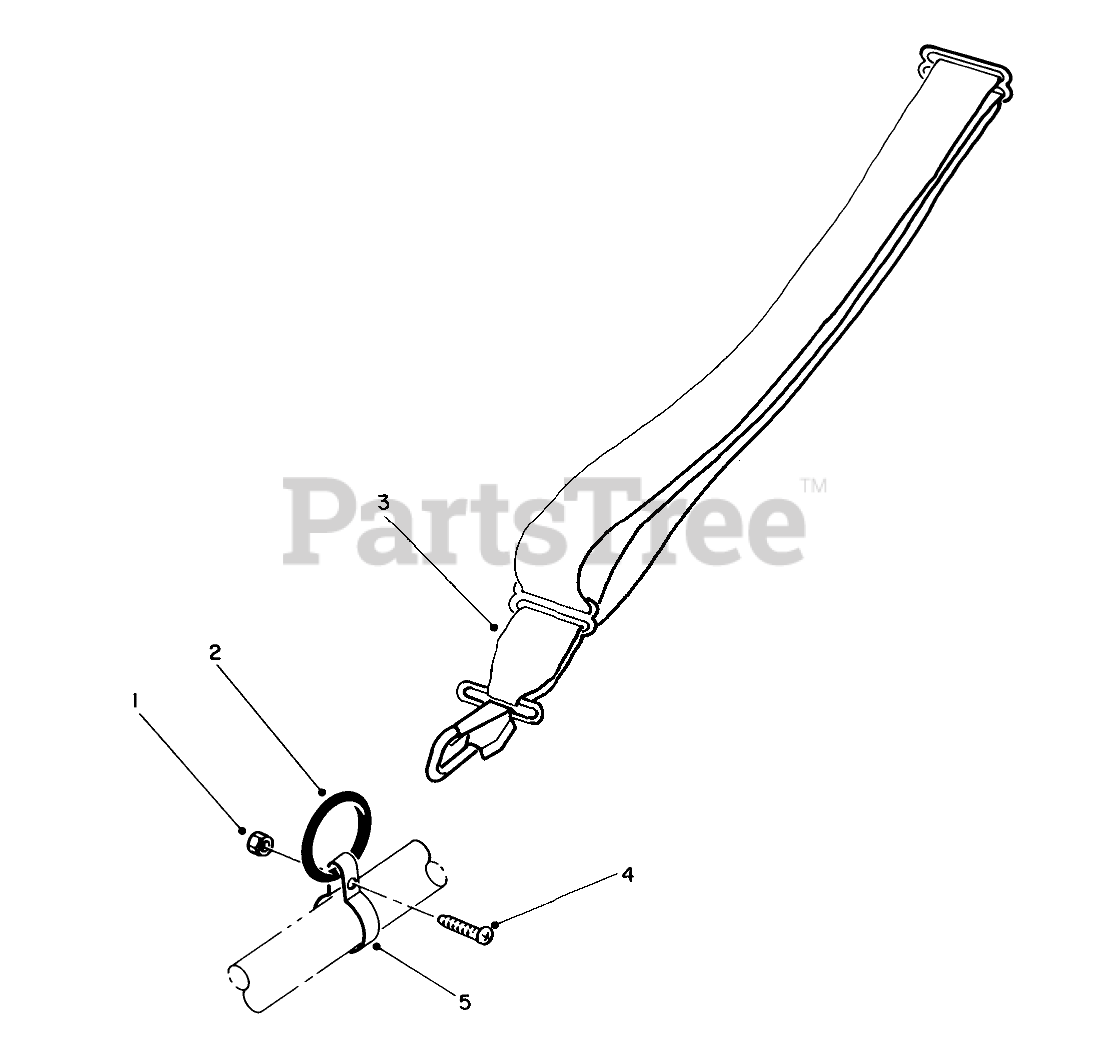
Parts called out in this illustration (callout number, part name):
1	NUT-LOCK, NI
2	RING-HARNESS
3	Harness
4	MANUAL
5	Clamp
